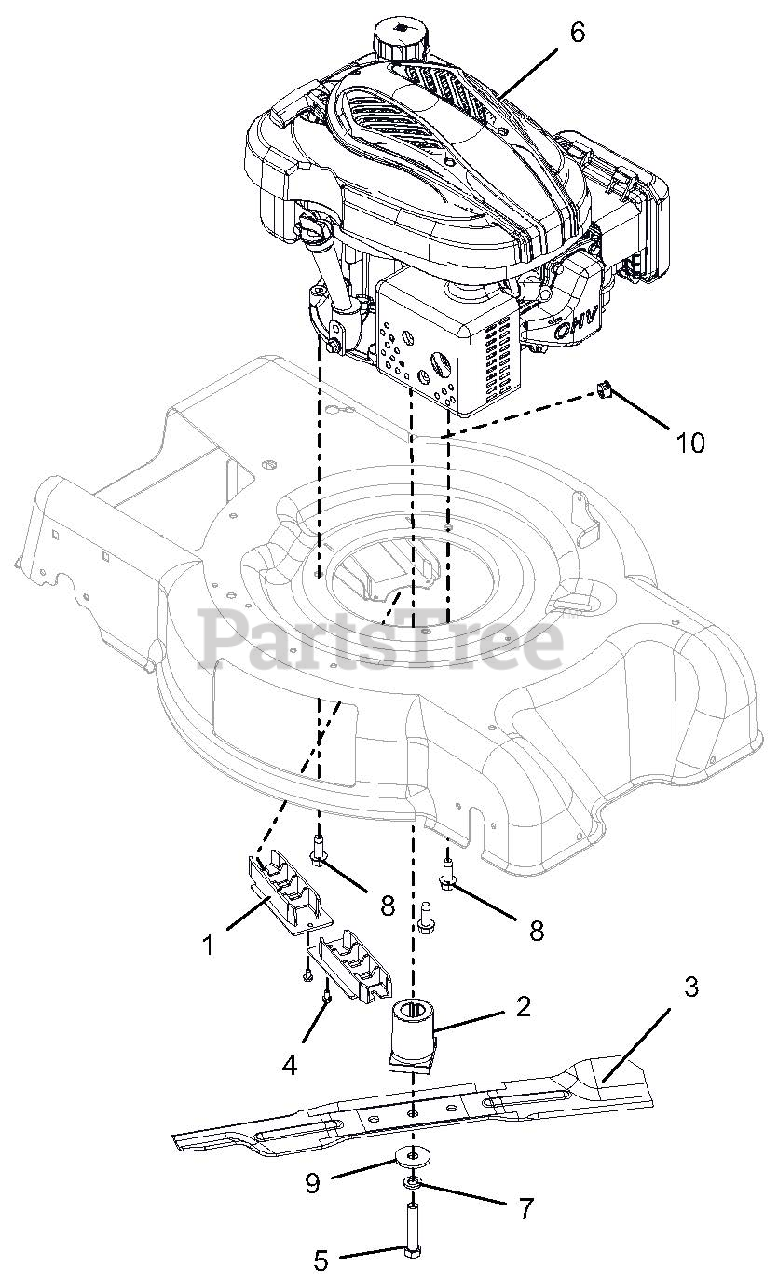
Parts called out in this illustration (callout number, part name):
1	GUIDE, BELT INNER
2	ADAPTOR, BLADE
3	BLADE, MOWER 21" HIGH-LIFT
4	SCR, TAP 10-24X.375 PRE-COAT 80
5	BLT-HEX .44-20X2.25 GR8 YWZC
6	ENGINE, 159CC VERT
7	WSHR-LK .44X.109 REG YWZC
8	SCR-TAP .38-16X1.00 HWH TR YZ
9	WSHR-FL-STL .4375X1.50X.125 YWZC
10	PLUG, DOME-BLACK, .625 DIA
